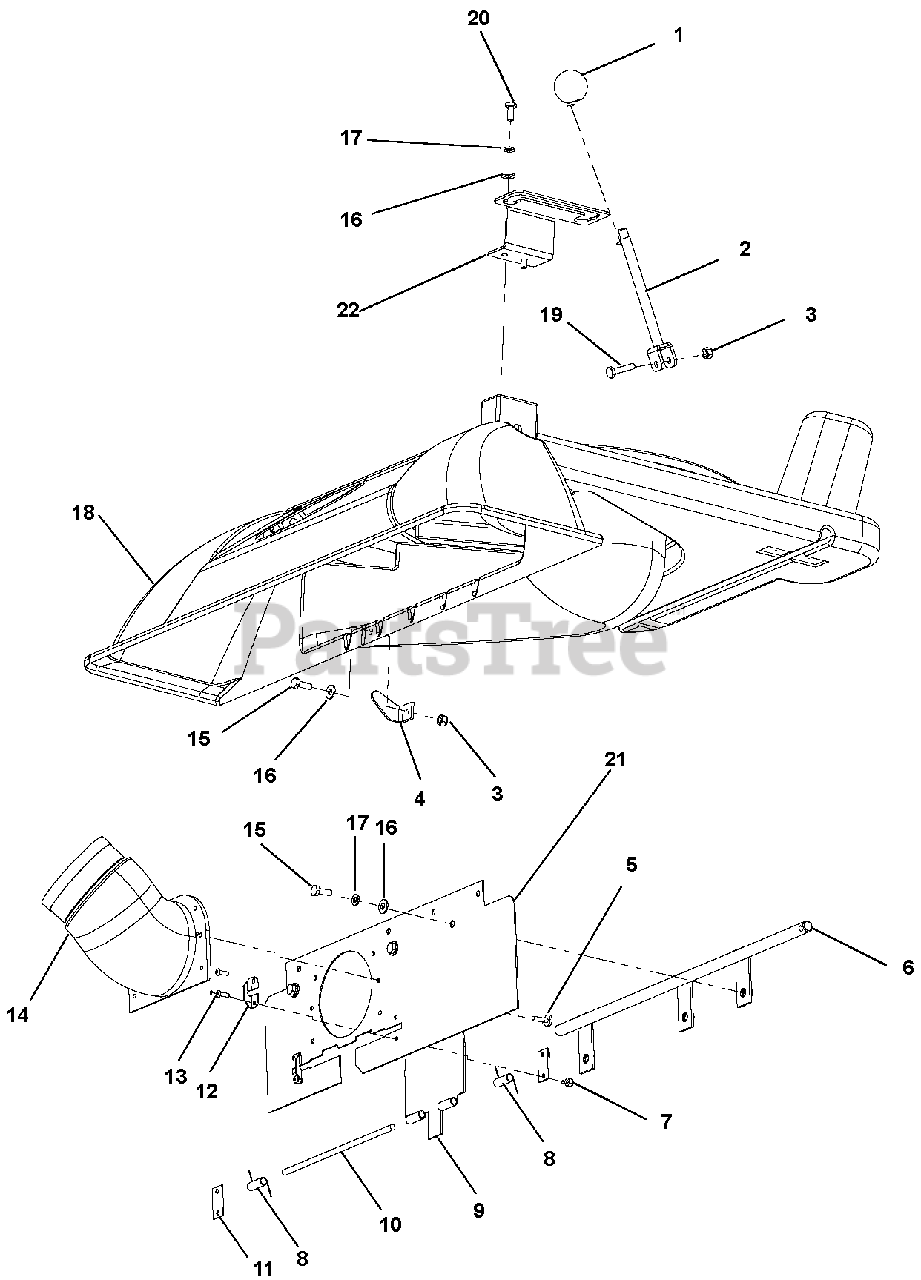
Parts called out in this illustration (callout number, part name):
1	Knob, Ball, Black 1.47" .375-16
2	Lever Assembly, APV
3	Nut, Locking, Nylon .250-20
4	APV Activator, Secondary Flap
5	Bulb Tite Rivet
6	Hinge Assembly
7	Nut, Locking, Nylon 8-32 w/Insert
8	APV Spring, Hose Door
9	APV Secondary Flap Weldment
10	APV Hinge Pin, Secondary Flap
11	APV Retaining Bracket, Secondary Flap
12	Clamp, Diverter Shaft, APV
13	Screw, 8-32 x .50, Pan, Allen
14	APV Adapter Flange, Hose, '07 Red
15	Bolt, Hex .25-20 x .75
16	Washer, Flat, Steel .281 x .62 x .065
17	Washer, Locking .25 x .062 Regular
18	APV Main Housing, w/Hose, '07 Red
19	Bolt, Hex .25-20 x 1.25
20	Bolt, Hex .25-20 x .63
21	Diverter Flap, APV
22	Lever Stop, APV
